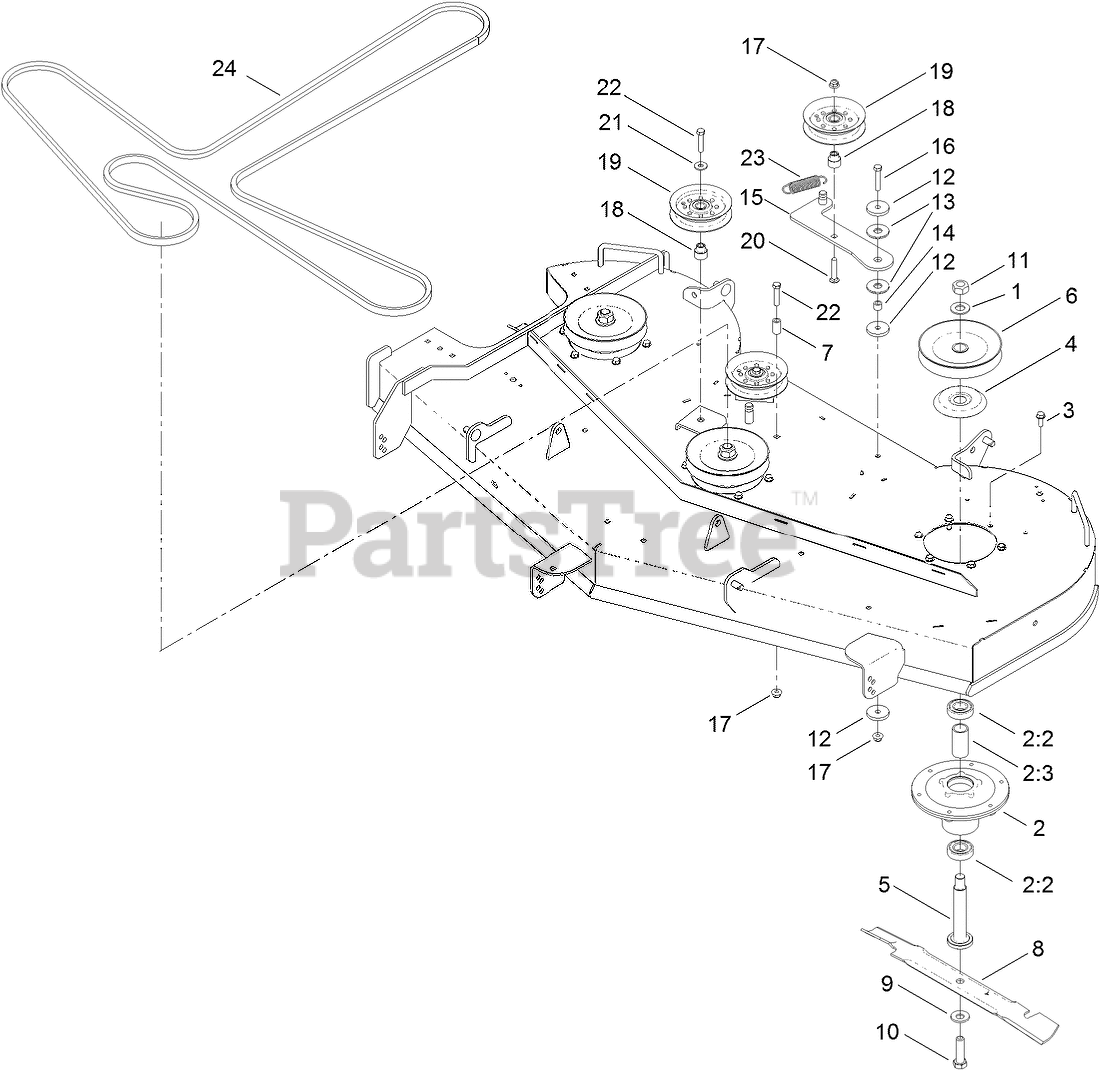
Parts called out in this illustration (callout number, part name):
1	WASHER
2	SPINDLE ASM
2:2	BEARING-BALL
2:3	SPACER-BEARING
3	SCREW-TAPTITE
4	SHIELD-BEARING
5	SHAFT-SPINDLE
6	PULLEY
7	SPACER
8	BLADE-HI FLOW, 20.5 INCH
9	WASHER-BELLEVILLE
10	SCREW-BLADE
11	NUT-HEX
12	WASHER-PLAIN
13	WASHER-FRICTION, COMPOSITE
14	BUSHING-LEVER, LIFT
15	ARM-IDLER
16	SCREW-HH
17	NUT-HF, NI
18	BUSHING-IDLER
19	PULLEY-IDLER
20	SCREW-CARR
21	WASHER-HARDENED
22	SCREW-HH
23	SPRING-EXTENSION
24	BELT-V
